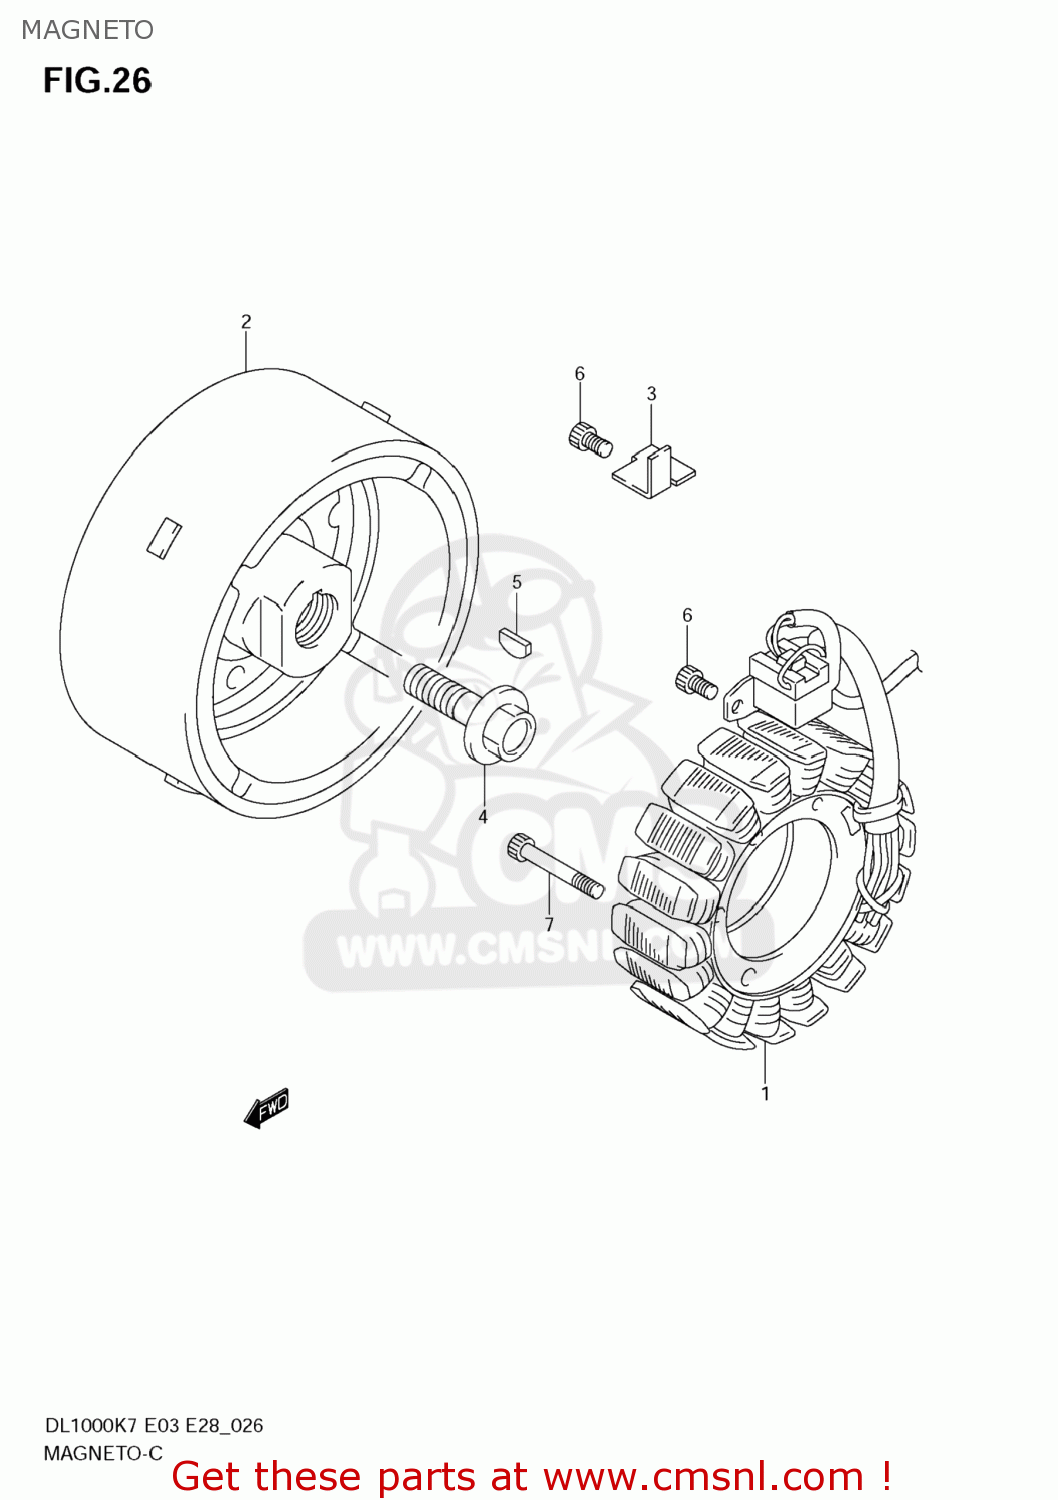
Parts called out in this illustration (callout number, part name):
1	STATOR ASSY,MA
2	ROTOR ASSY
3	CLAMP,MAGNETO LEAD NO.1
4	BOLT,MAGNETO ROTOR
5	KEY
6	BOLT
7	BOLT(6X35)
